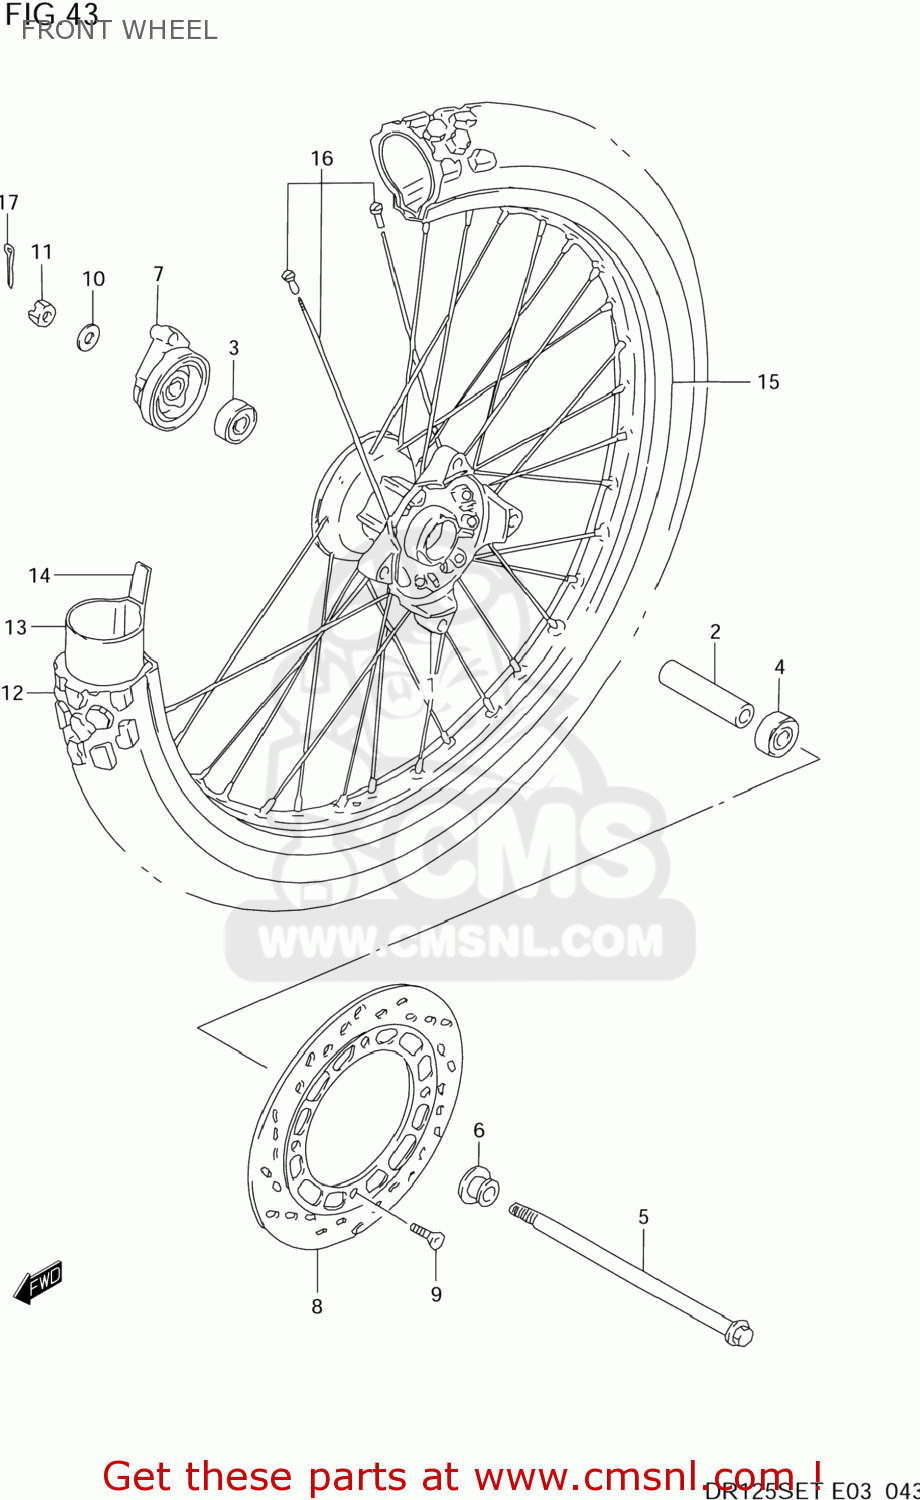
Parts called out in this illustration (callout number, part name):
1	HUB,FR
2	SPACER (12.6X19X60.5)
3	BEARING
4	BEARING (12X32X10)
5	AXLE,FR
6	SPACER,FR AXLE
7	BOX ASSY,SPEEDOMETER GEAR
8	DISC,FR BRAKE
9	BOLT,BRAKE DISC
10	WASHER
11	NUT
12	TIRE,FR(70/100-21 44P)
13	TUBE
14	PROTECTOR,WHEEL INNER
15	RIM,FR WHEEL(21X1.60 FE)
16	SPOKE SET,FR WHEEL
17	COTTER PIN
